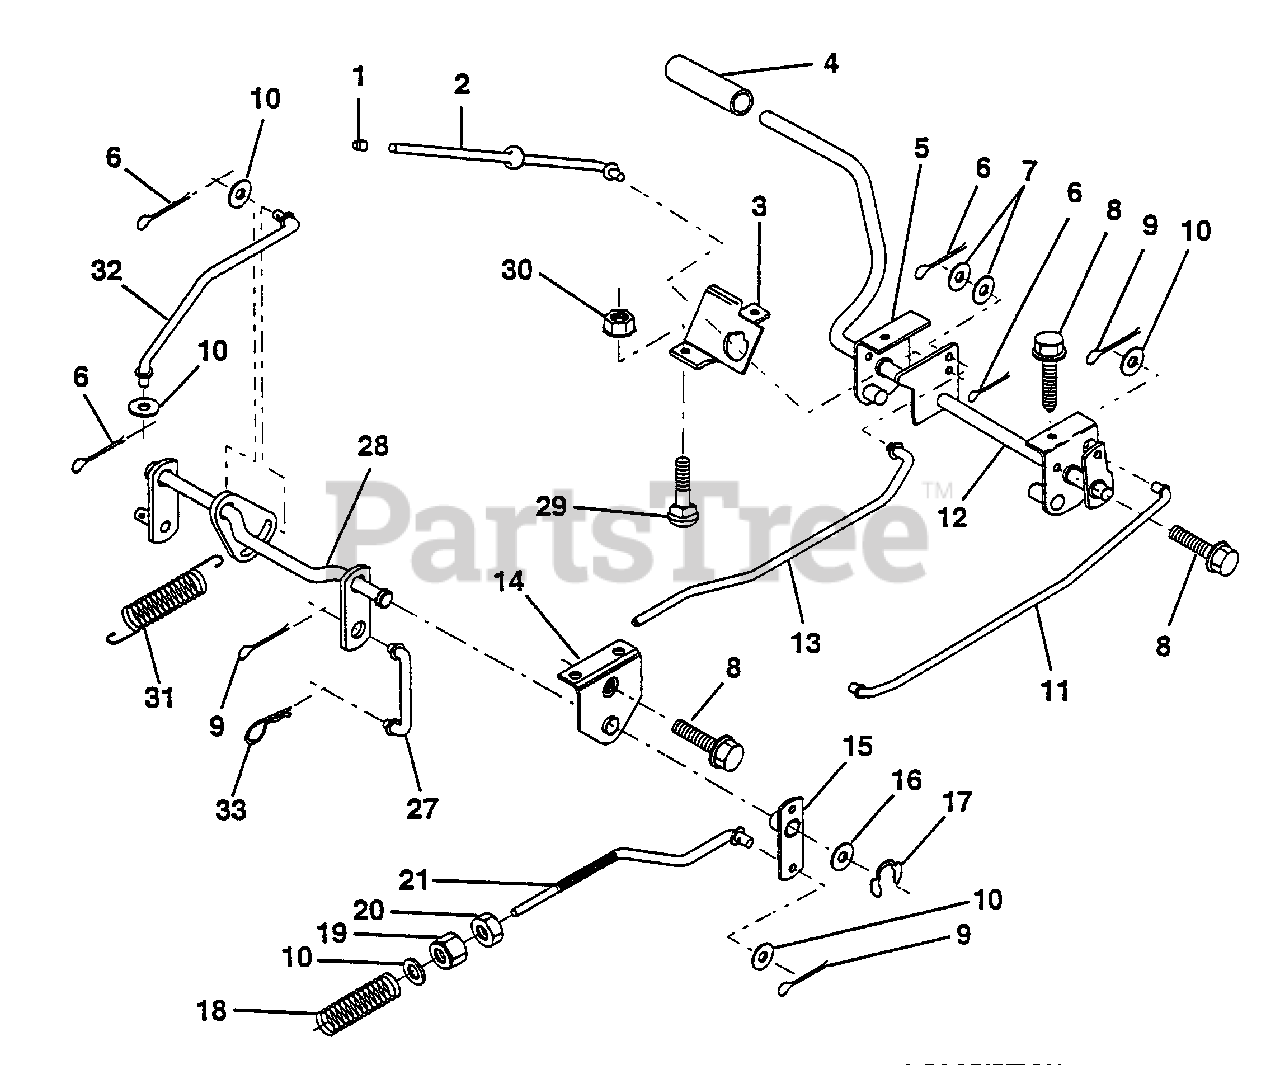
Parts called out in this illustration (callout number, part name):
1	Cap, Plunger
2	Rod, Parking Brake
3	Bracket, Parking Brake
4	Cover, Pedal
5	Bracket, Clutch/Brake Pedal, L.H.
6	Pin, Cotter 3/32 x 3/4
7	Washer 13/32 x 5/8 x 16 Gauge
8	Screw, Hex Head, Thd., Roll. 5/16-18 x 1/2
9	Pin, Cotter 1/8 x 3/4
10	Washer 13/32 x 13/16 x 16 Gauge
11	Rod, Brake, Front
12	Assembly, Clutch/Brake Pedal
13	Rod, Clutch
14	Bracket, Lift Shaft
15	Assembly, Brake, Pivot, Arm
16	Washer 25/32 x 1-1/8 x 16 Gauge
17	Ring, Klip
18	Spring, Brake Rod
19	Nut, Hex, Jam 3/8-16 UNC
20	Locknut, Hex, w/Wsh Ins 3/8-16 UNC
21	Rod, Brake, Rear
27	Link, Lift, Rear
28	Assembly, Rear Mower Lift
29	Bolt, Carriage 5/16-18 UNC x 3/4
30	Nut, Hex, Keps 5/16-16 UNC
31	Spring, Counterbalance
32	Link, Lift Lever
33	Retainer Spring
